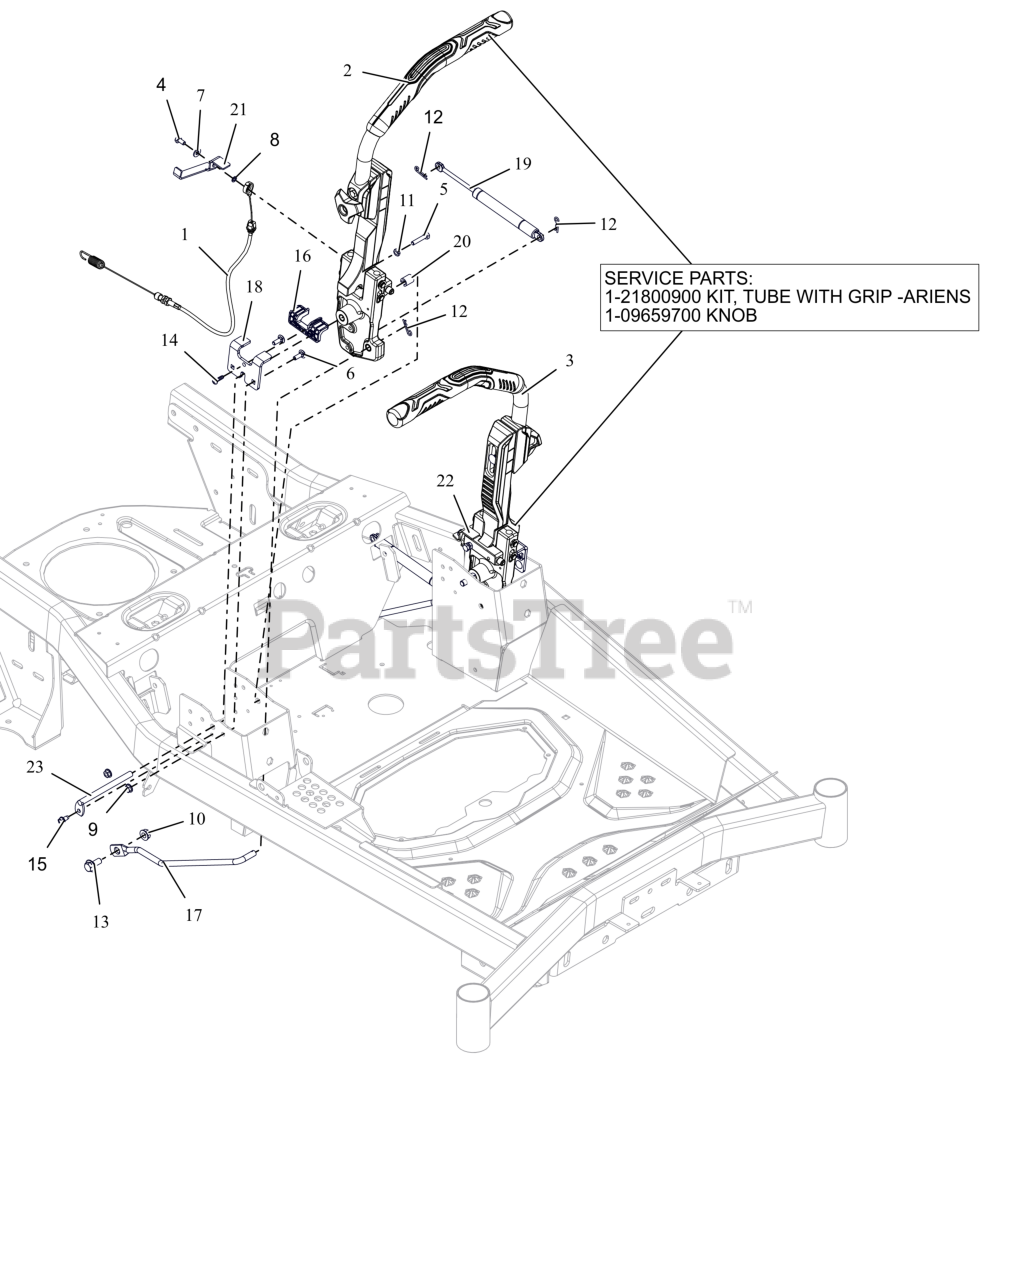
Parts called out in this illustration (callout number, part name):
1	CABLE- PARK BRAKE
2	ASM- CONTROLS -RH
2	KIT - TUBE WITH GRIP - ARIENS
2	KNOB, STEERING ADJUSTMENT
3	ASM- CONTROLS -LH
4	BLT, HEX .25-20X.50 G5ZCC EP80
5	BLT, HEX 0.25-20X1.25F GR5 ZCC
6	BLT, RHSN .25-20X.750 G5 ZCC
7	WSHR,FLT .281X.625X.065 ZCC
8	WSHR-FL-STL 0.25X0.406X0.05 ZCC
9	NUT-LK-CTR-FLG .25-20 ZC120
10	NUT-LK-CTR-FLG .375-16 GF ZCC
11	NUT-JAM .250-20 G2 ZCC
12	PIN, HAIR #213 .08X1.19 ZCC
13	BLT-SHLDR .50X.175 ZCC
14	SCR-TAP 12-14X.75PLSTITE @BLZC
15	SCR-TAP .25-20X.50 HWH ZCC
16	STEERING-PLASTIC LINER
17	WIREFORM- STEERING LINKAGE
18	PLATE- BRAKE STOP
19	DAMPER- STRAIGHT MOUNT
20	SPCR- SNAP-ON 1/2 X 1 1/2
21	BRKT, PARKING BRK ENG R (BLACK)
22	BRKT, PARKING BRK ENG L (BLACK)
23	PIN- FIXED STEERING PIVOT
